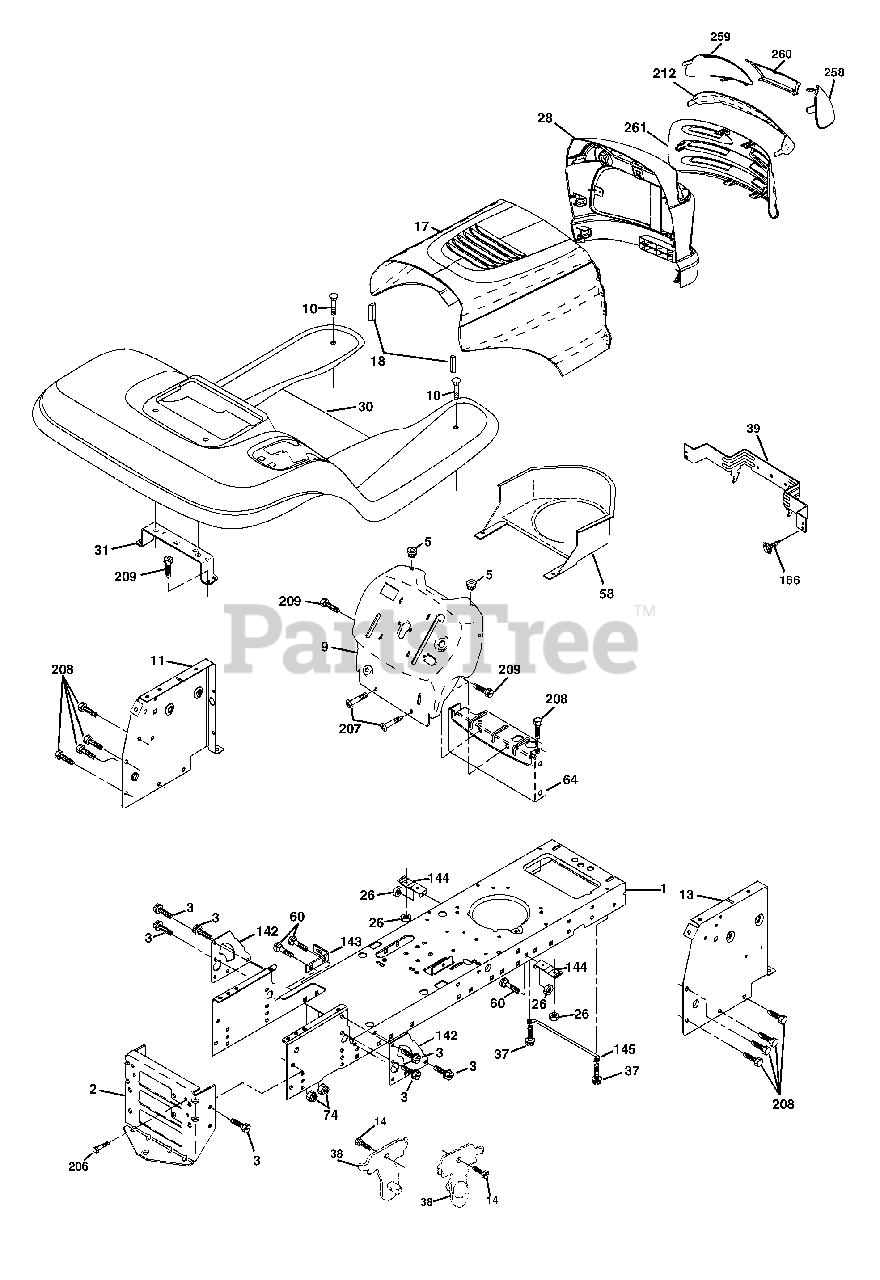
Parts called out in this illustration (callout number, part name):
1	Chassis Stamping
3	Screw 3/8-16x3/4
9	Dashboard
10	Bolt Rdhd Sqnk 3/8-16 Unc x 1
11	Panel Dash Lh
13	Panel Dash Rh
14	Screw Thdrol 3/8-16 x 1/2
17	Hood
18	Bumper Hood
26	Nut Lock w/Insert 3/8-16 UNC
28	Grille Lens Asm
30	Fender
37	Screw Thdrol 5/16-18 x 1/2
38	Bracket Asm Pivot Mower Rear
39	Bracket Pivot Hood
60	Bolt RDHD SQNK 3/8-16 x 3/4
64	Dash Lower Stlt
74	Nut Crownlock 3/8-16
142	Plate Reinforcement Stlt
143	Bracket Swaybar Chassis
144	Bracket Ft Rest
145	Rod Pivot Chassis Hood
166	Screw Hw Hd Hi-Lo #13-16 x 3/4
206	Bolt Shoulder 5/16-18 TT
207	Screw Thdrol 5/16-18 x 1/2 TYTT
208	Screw Thdrol 3/8-16 x 1/2 Ty-TT
209	Screw 3/8-16 x 3/4
212	Insert Lens Reflect
258	Lens RH
259	Lens LH
260	Cover Lens
261	Insert, Grille
